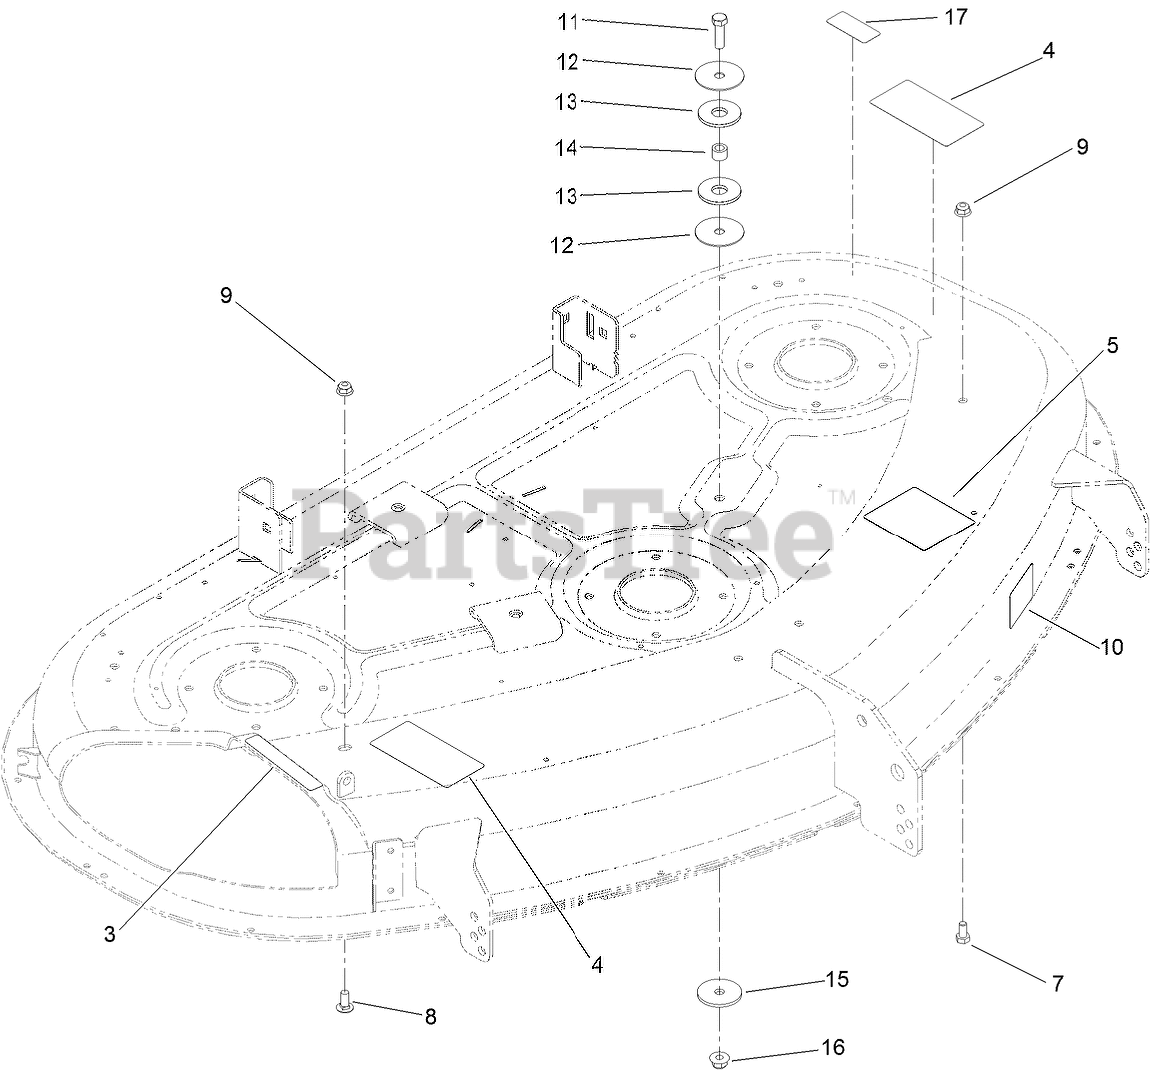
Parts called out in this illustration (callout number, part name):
3	DECAL-DANGER
4	DECAL-DANGER, DECK
5	DECAL-ROUTING, BELT
7	SCREW-HH
8	SCREW-CARR
9	NUT-HF, NI
10	DECAL-SCALP, ANTI
11	SCREW-HH
12	WASHER
13	WASHER-FRICTION, COMPOSITE
14	SPACER
15	WASHER-REBOUND
16	NUT-HF, NI
17	DECAL-SERVICE DECK
